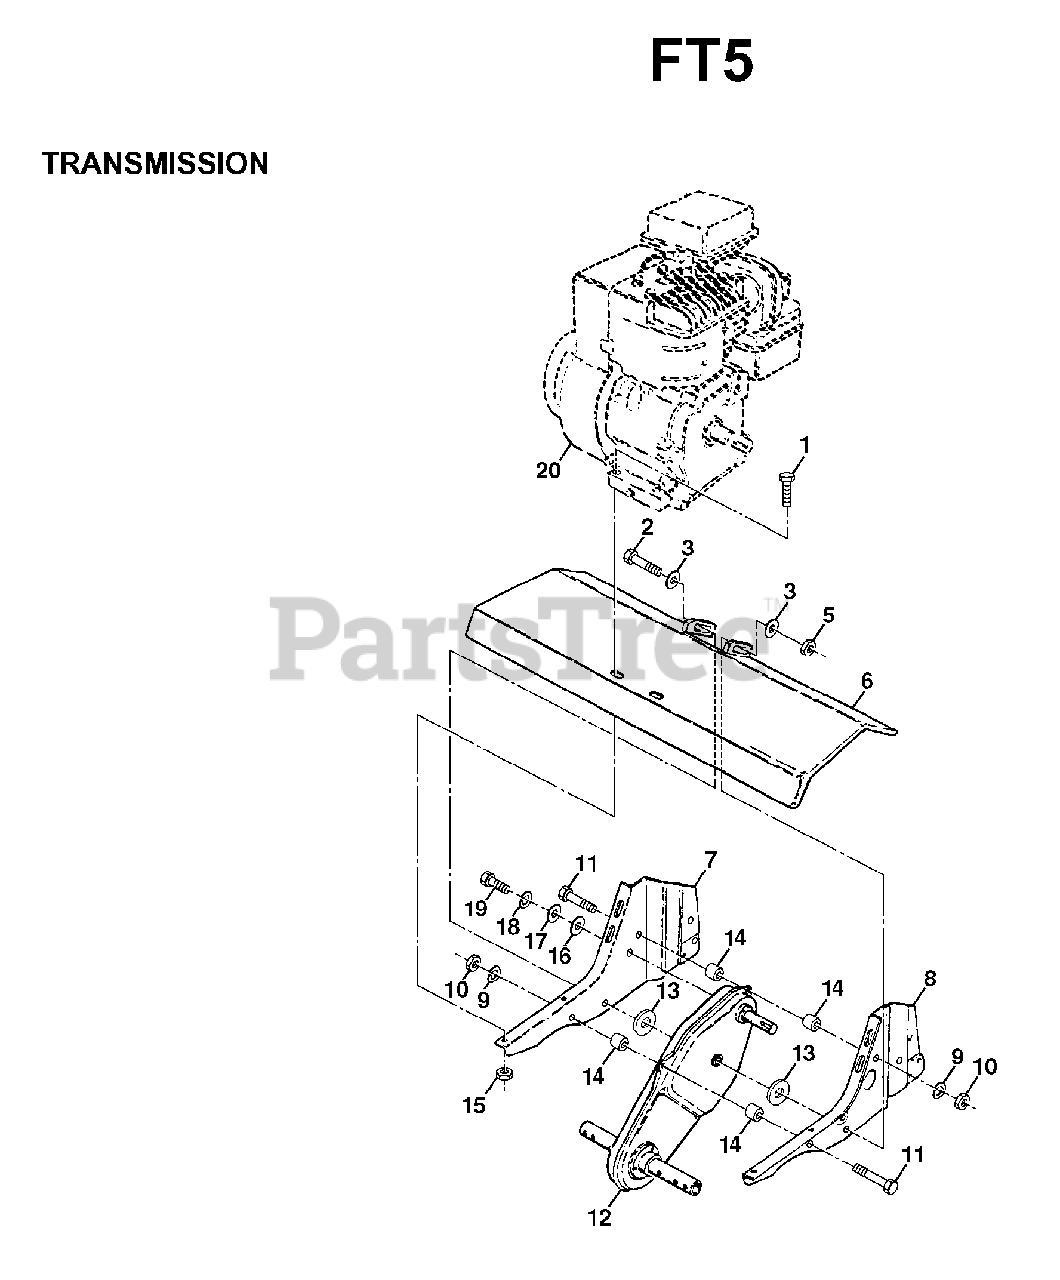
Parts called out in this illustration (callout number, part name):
1	BOLT
3	WASHER
5	NUT
9	LOCKWASHER
11	BOLT
12	TRANSMISSION.ASM.W/1".D-SHAFT
13	WASHER
15	NUT
18	LOCKWASHER
